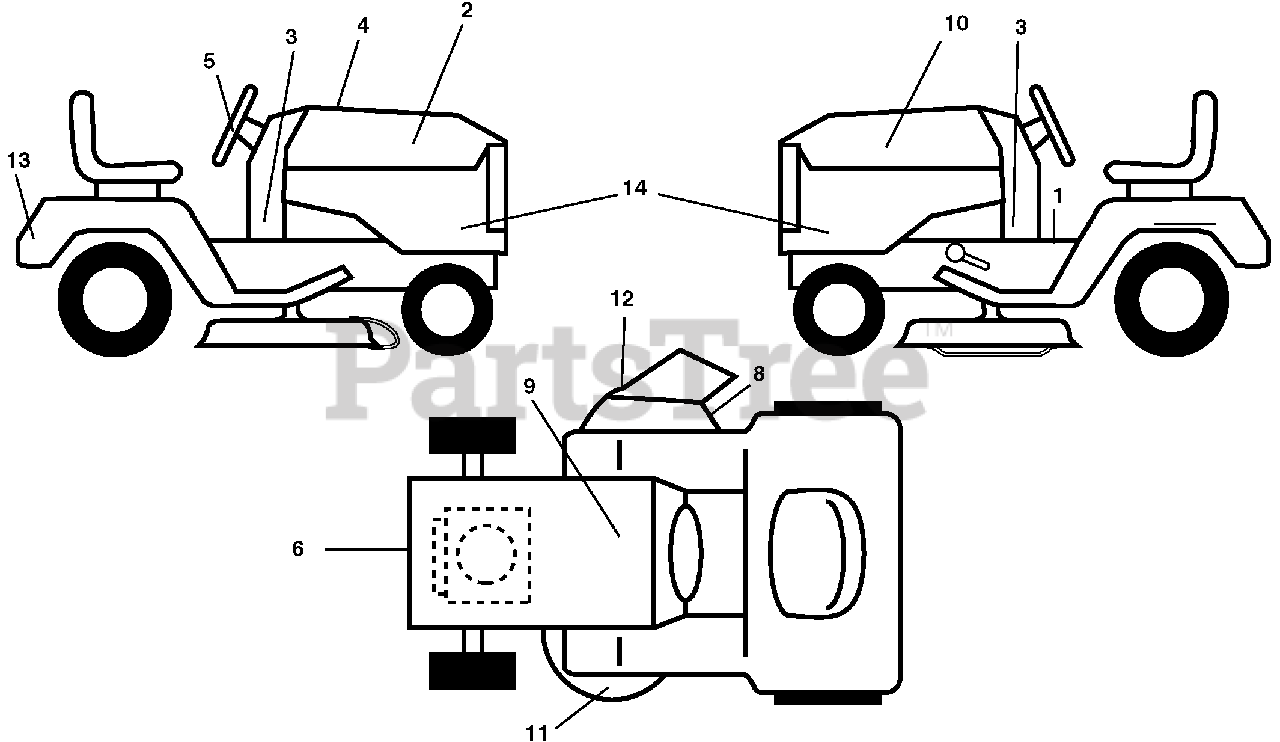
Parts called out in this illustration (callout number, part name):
1	Decal, Operator's
2	Decal, Hood RH
3	Decal, Dash LWR
4	Decal, Replacement
5	Decal, Strg Whl
6	Decal, Engine HP
8	Decal, Mower Sch.
9	Decal, Battery Dnge/Poi
10	Decal, Hood LH
11	Decal, Mower Caution
12	Decal, Mower Warning Keep Hand Away
13	Decal, Fender
14	Decal, Panel SD
14	Decal, Bypass
14	Pad, Footrest, LH
14	Pad, Footrest, RH
14	Manual, Operator's (Eng & French)
14	Manual, Parts
